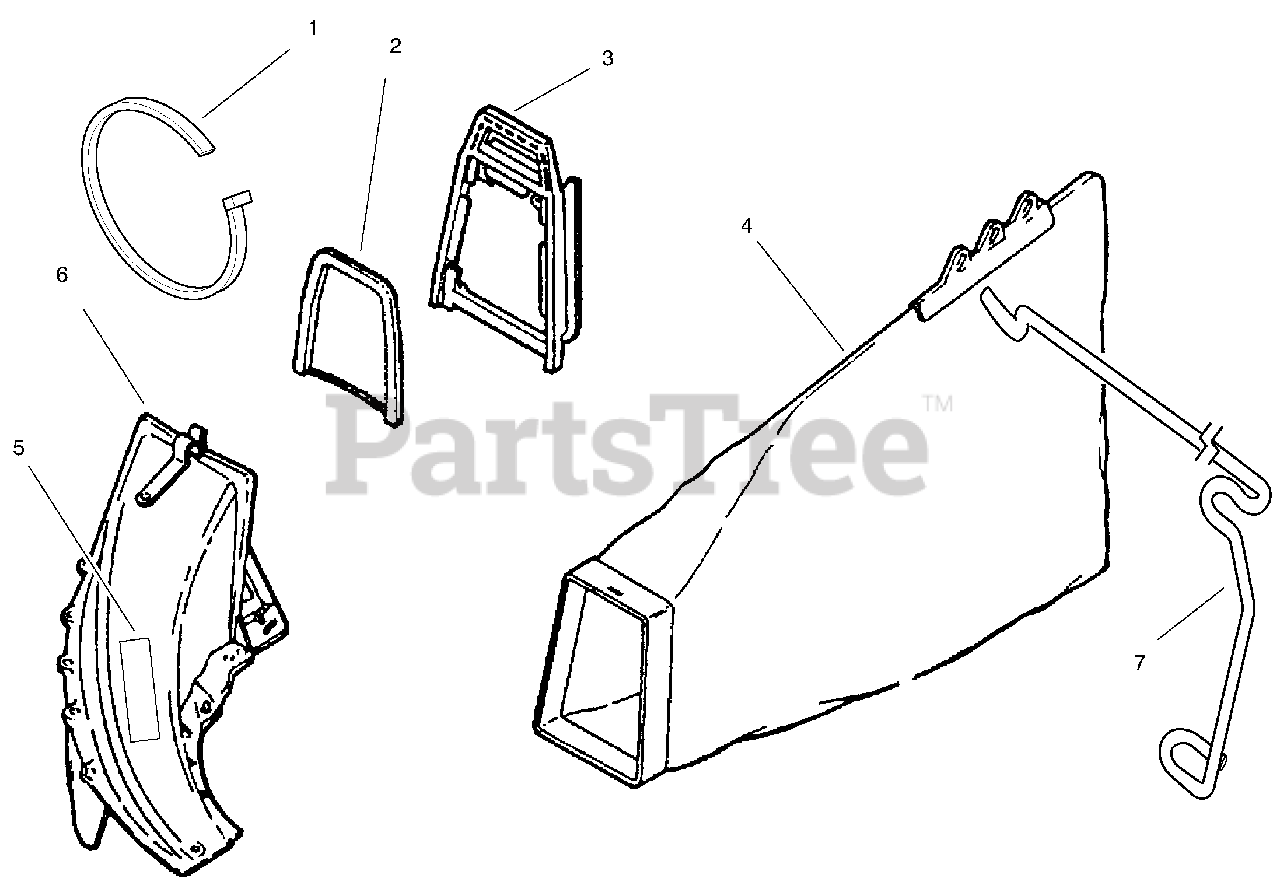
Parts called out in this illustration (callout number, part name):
1	Strap-Tie
2	Brace-Chute
3	Adaptor-Chute
4	Bag-Grass
5	Decal-Danger
6	Chute Assembly
7	Rod-Grass Bag
